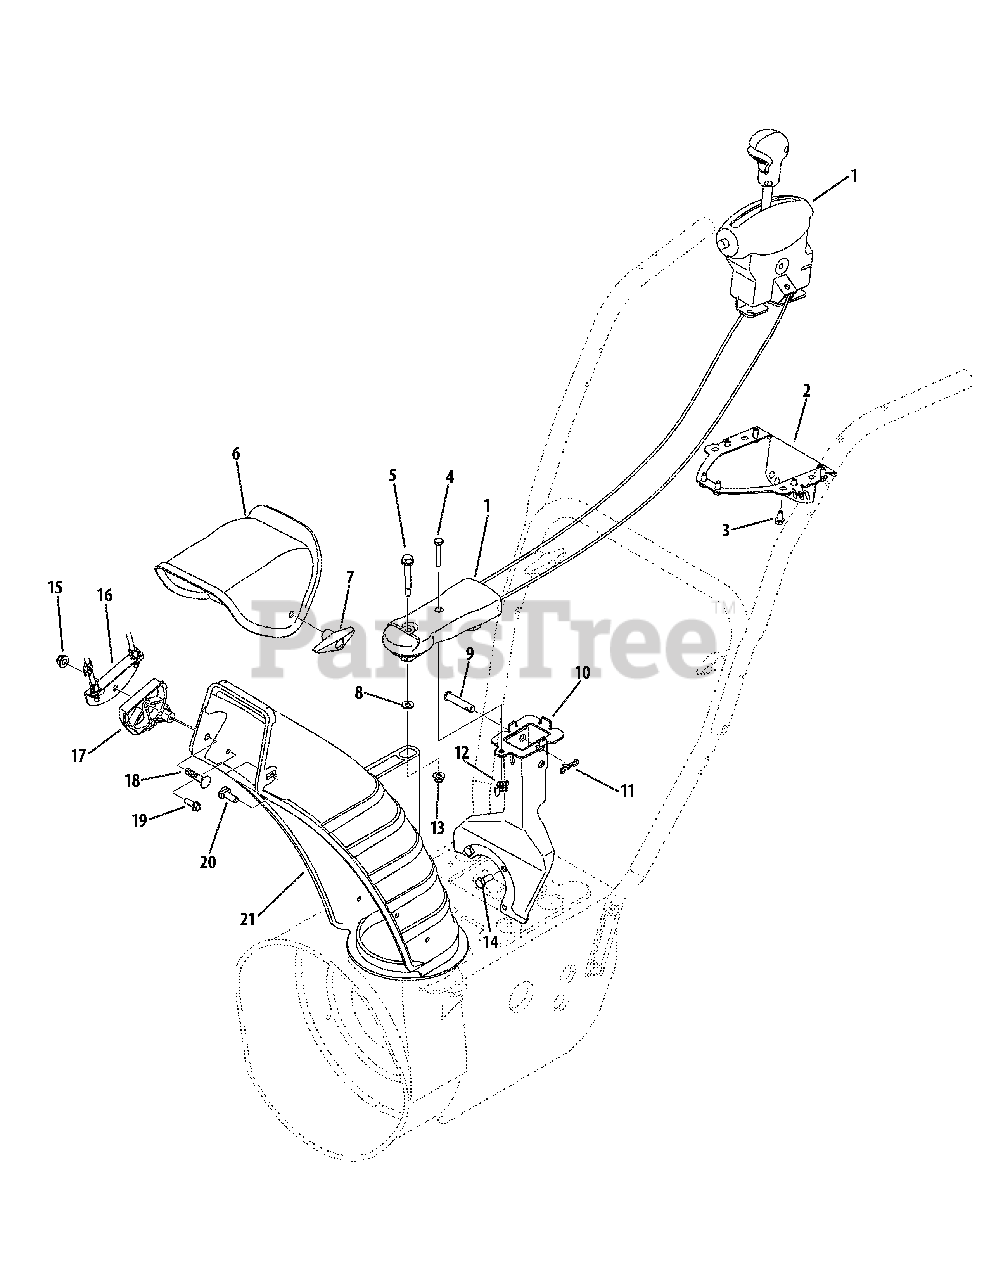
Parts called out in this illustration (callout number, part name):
1	Chute Control Assembly
3	Hex Washer Screw, 1/4-15 x .50
4	Hex Screw, 1/4-20 x 1.50
5	Shoulder Screw, .312 x 1.70 x 1/4-20
6	Upper Chute
7	Wing Knob, 5/16-18
8	Flat Washer, .25 x .630 x .0515
9	Clevis Pin, 3/8 x 1.87
11	Bow-Tie Cotter Pin
12	Wing Nut, 1/4-20
13	Flange Lock Nut, 1/4-20
14	Hex Lock Screw, 5/16-24 x .750
15	Flange Lock Nut, 5/16-18
17	Chute Tilt Cable Guide
18	Carriage Bolt, 5/16-18 x 1.50
19	Hex Washer Screw, 1/4-15 x .750
20	Carriage Bolt, 5/16-18 x 1.00
21	Lower Chute, 5.0
